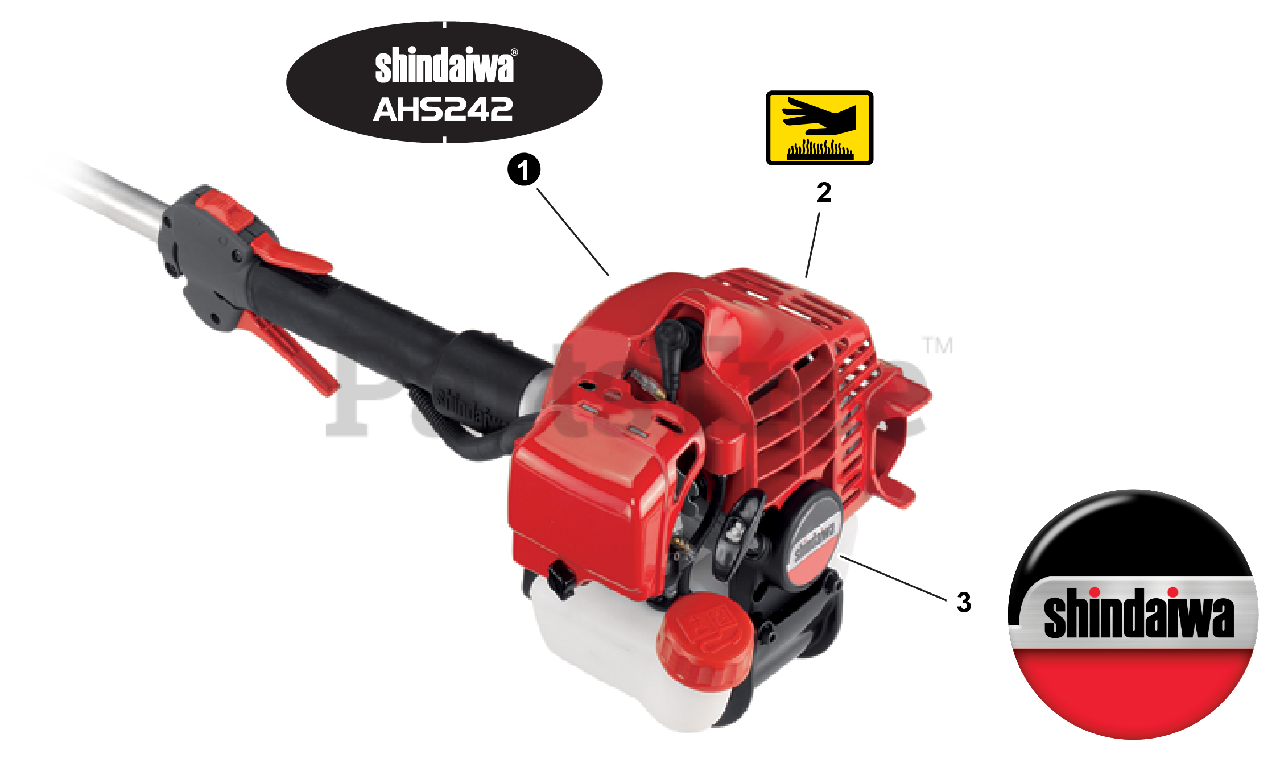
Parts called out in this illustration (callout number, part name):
1	LABEL - MODEL AHS242
2	LABEL, CAUTION - HOT
3	LABEL, RECOIL STARTER
